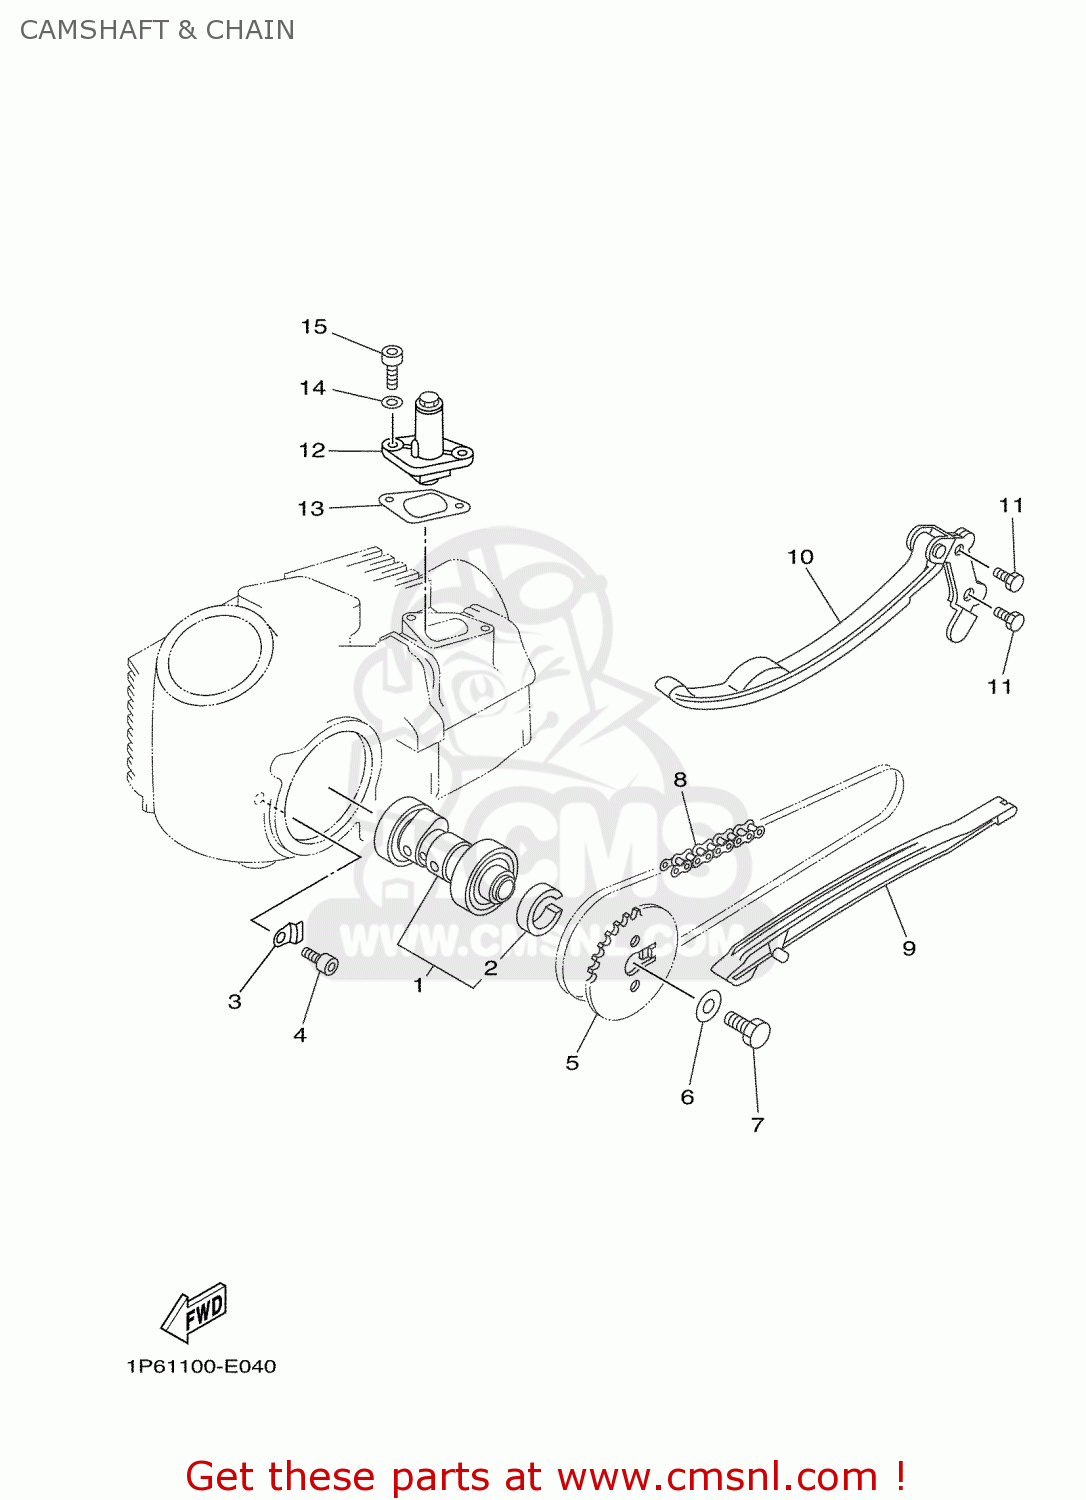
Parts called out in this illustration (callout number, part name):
01	CAMSHAFT ASSY 1
02	COLLAR(50M)
03	PLATE
04	BOLT, HEXAGON SOCKET HEAD
05	SPROCKET, CAM CHAIN
06	WASHER
07	BOLT
08	CHAIN
09	GUIDE, STOPPER 1
10	GUIDE, STOPPER 2
11	BOLT
12	TENSIONER ASSY, CAM CHAIN
13	GASKET, TENSIONER CASE (NAS)
14	GASKET (NAS)
